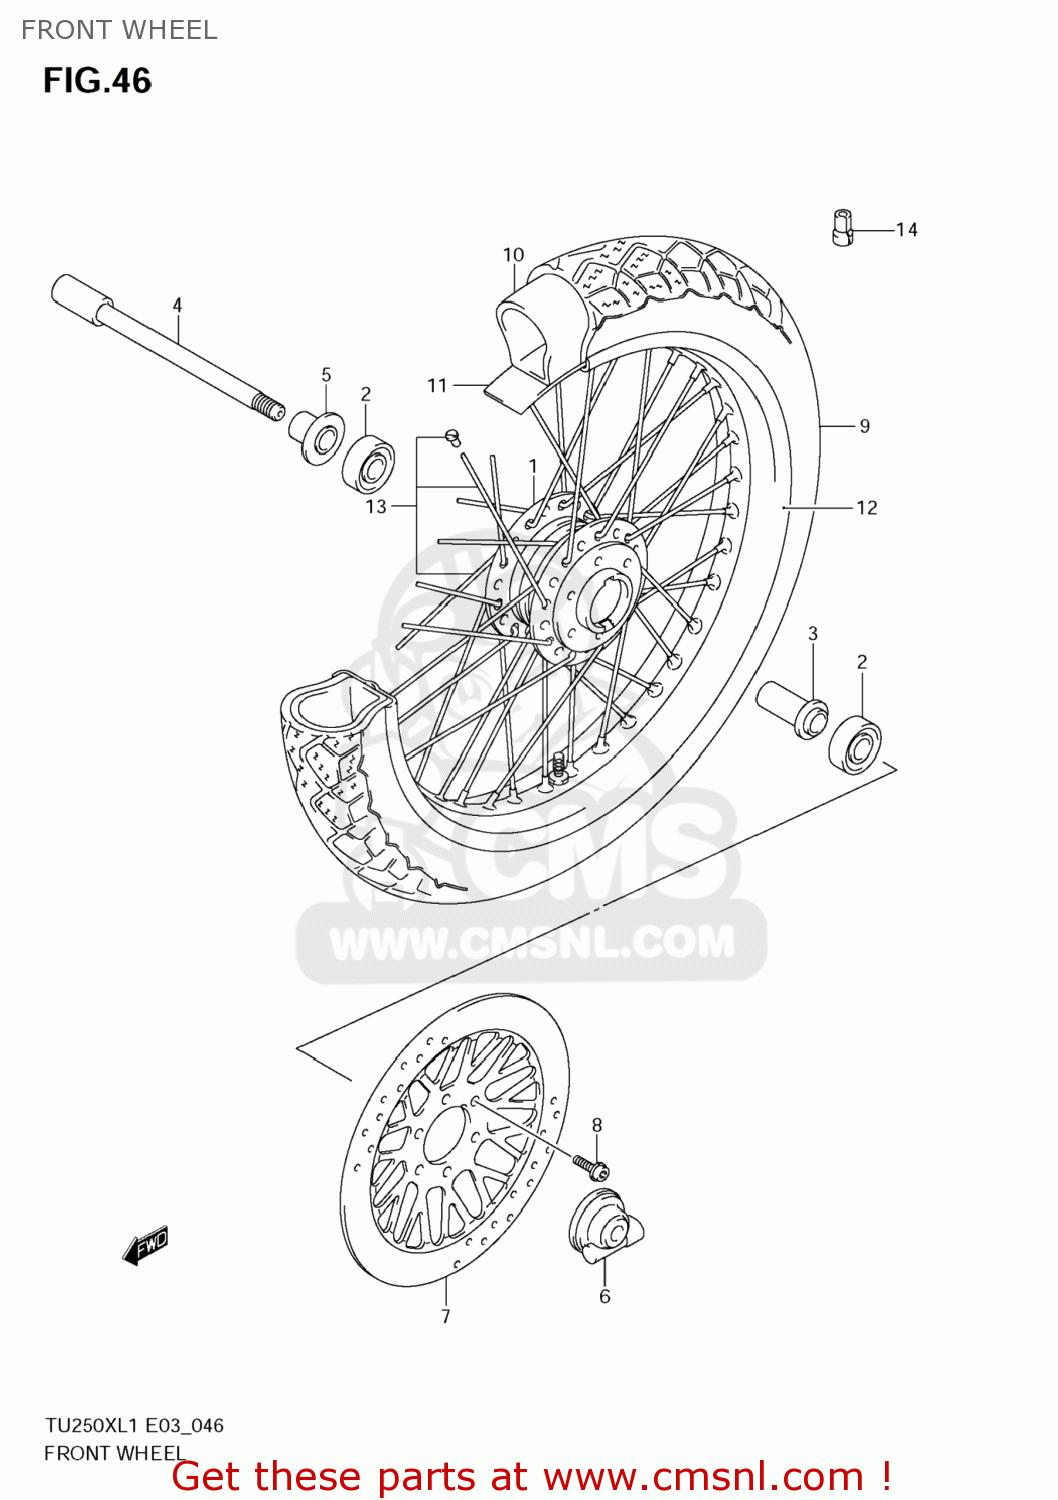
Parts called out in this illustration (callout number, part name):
1	HUB,FR WHEEL
2	BEARING
3	SPACER,FR HUB BEARING
4	AXLE,FR
5	SPACER,FR HUB BEARING,R
6	BOX ASSY,SPEEDOMETER GEAR
7	DISC,FR BRAKE,L
8	BOLT(8X30)
9	TIRE,FR
10	TUBE ASSY,WHEEL INNER
11	PROTECTOR,WHL INR TUBE
12	RIM,FR WHEEL(1.85X18)
13	SPOKE ASSY,FR WHEEL
14	BALANCER,WHEEL(15G)
